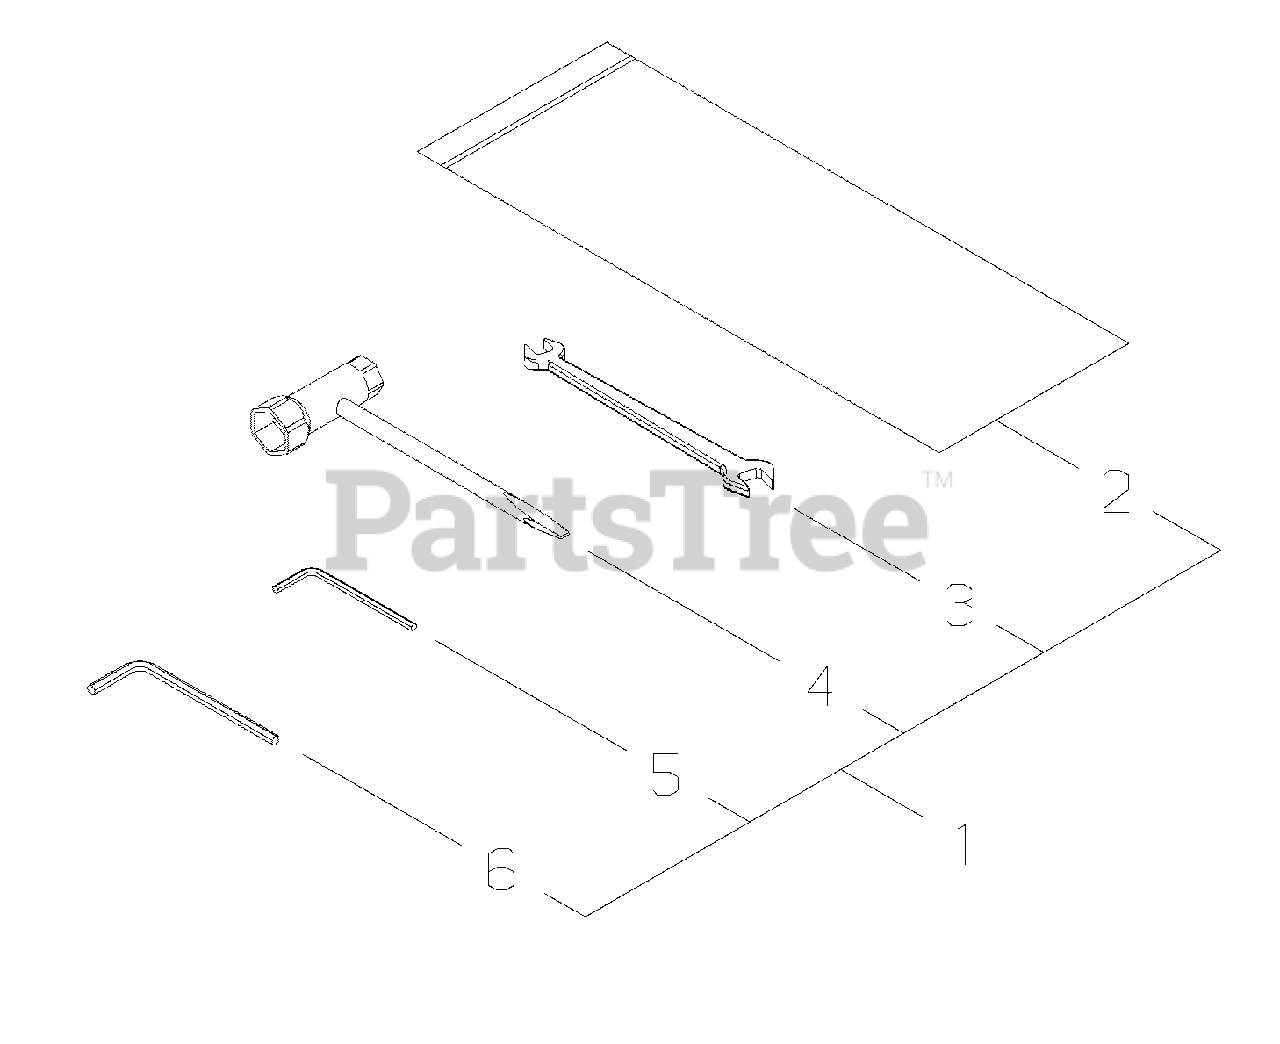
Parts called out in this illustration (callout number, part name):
1	TOOL KIT, SERVICE
2	BAG, TOOL
3	SPANNER 8×10
4	T-WRENCH 16×13
5	WRENCH, ALLEN 3 MM
6	WRENCH, ALLEN 4 MM
